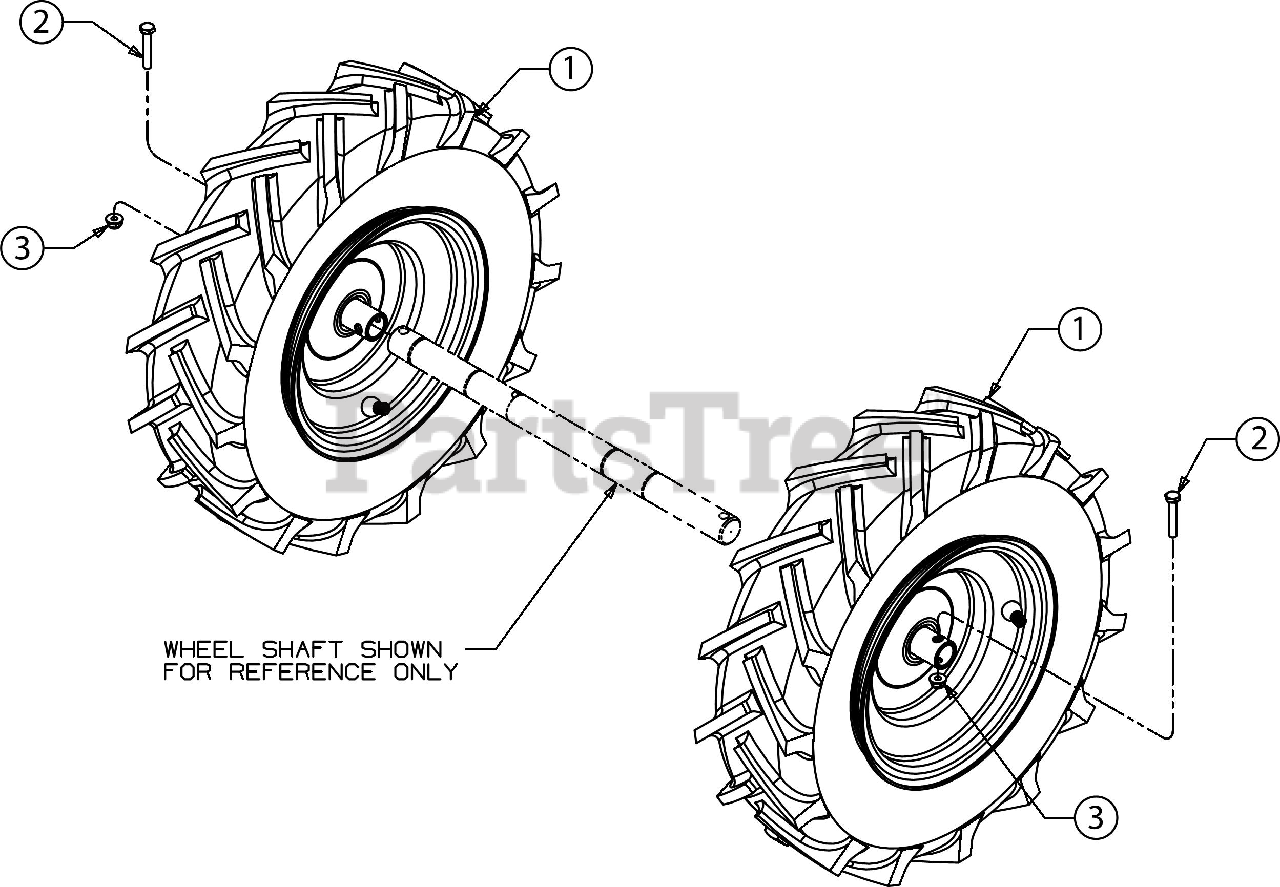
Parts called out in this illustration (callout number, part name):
1	WHEEL ASSEMBLY (16 X 4.6 X8) (BEIGE)
1	RIM ASSEMBLY (8 X 3.75 X .757) (BEIGE)
1	TUBELESS VALVE
1	TIRE 16.25 X 4.5-8
2	SCREW 1/4-20 X 1.50 GR8
3	FLANGE LOCK NUT
